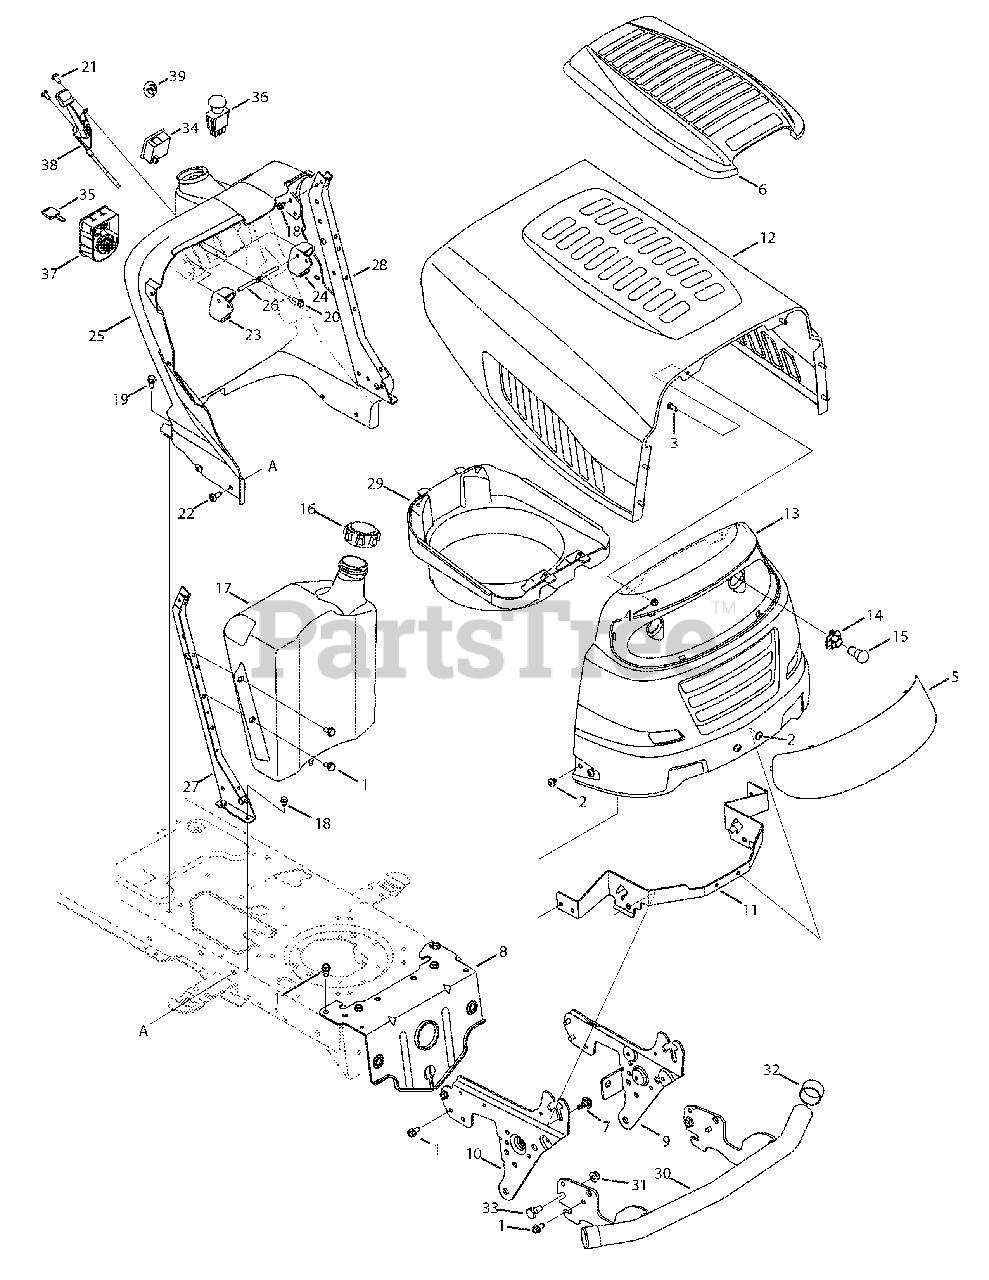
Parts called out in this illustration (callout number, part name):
1	Screw, 5/16-18 x .750
2	Screw, 5/16-18 x .375
3	Hex Cap Screw, 1/4-20 x.62
4	Flange Lock Nut, 1/4-20
5	Headlight Lens
6	Cover Hood 5-Style
7	Shoulder Screw,.43 x.29
8	Pivot Bar Bracket
9	Pivot Support Bracket - LH
10	Pivot Support Bracket - RH
11	Hood Pivot Bracket
12	Hood, 5 Style
13	Grille, 1 Style
14	Headlight Socket
16	Fuel Cap
17	Fuel Tank, Three Gallon
18	Self-tapping Screw, 1/4-20 x.5
19	Screw, 5/16-18 x .500
20	Self-tapping Screw, 1/4-15 x.75
21	Screw, 1/4-14 x.625
22	Screw, 5/16-18 x.75
23	Cruise Control Button
24	Parking Brake Button
25	Dash Panel
26	Brake/Cruise Pivot Rod
27	RH Dash Support Plate
28	LH Dash Support Plate
30	Bumper Assembly
31	Flange Lock Nut, 3/8-16
33	Shoulder Bolt, 3/8-16
34	Systems Ind. Monitor w/Hr. Mtr.
35	Ignition Key w/ plastic cover
36	Electric PTO Switch
37	Ignition Switch
38	Throttle Control/Cable
39	Choke Plug
